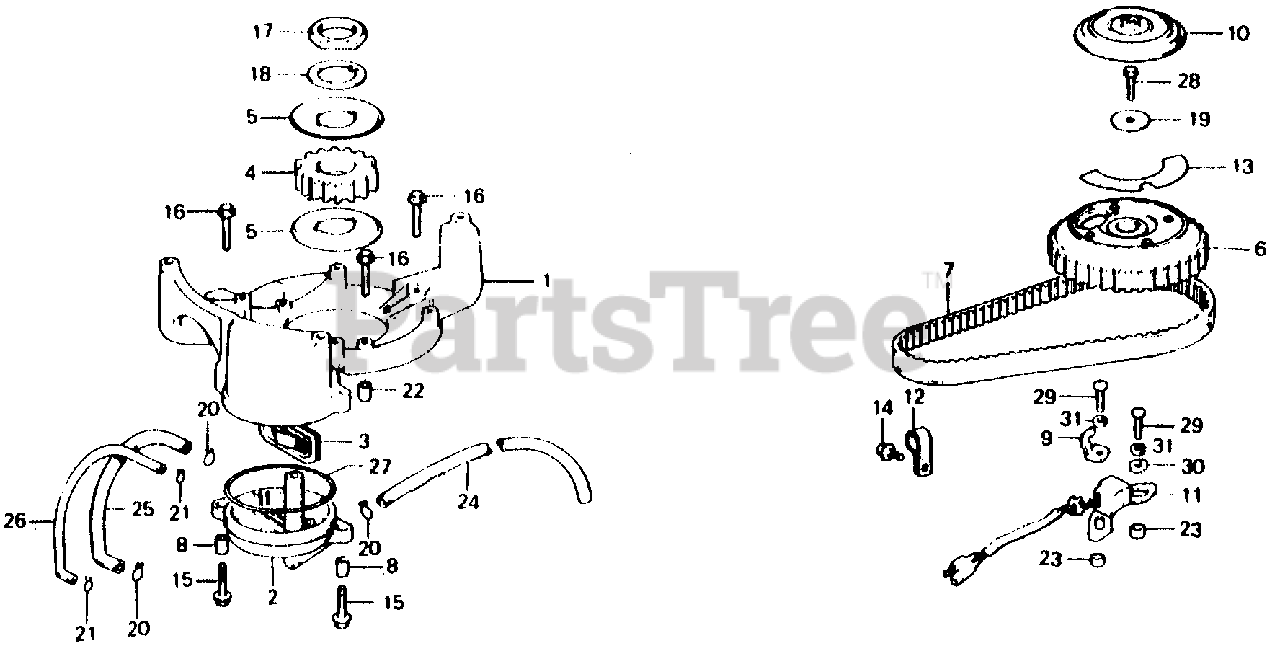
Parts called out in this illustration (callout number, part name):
1	CASE, STARTER *NH8* (DARK GRAY)
2	COVER, BREATHER
3	BODY, VALVE
4	PULLEY, TIMING
5	FLANGE, TIMING PULLEY
6	PULLEY, CAMSHAFT
7	BELT, TIMING
8	COLLAR A, DISTANCE
9	PLATE, WIRE CLAMP
10	COVER, POINT
11	COIL ASSY., PULSER (NOT AVAILABLE)
13	MARK, POINT
15	BOLT, FLANGE (6X22)
16	BOLT, FLANGE (6X28)
17	NUT, LOCK (24MM)
18	WASHER, LOCK (24MM)
19	WASHER, WHEEL (6MM)
20	CLIP, TUBE (B12)
21	CLIP B7, TUBE
22	PIN, DOWEL (8X10) (NOT AVAILABLE)
23	PIN, DOWEL (7X4.5)
24	TUBE B, BREATHER (NOT AVAILABLE)
25	TUBE C, BREATHER
26	TUBE, OIL RETURN
27	O-RING (62X2.5)
28	BOLT, HEX. (6X22)
29	SCREW, PAN (5X14)
30	WASHER, PLAIN (5MM)
31	WASHER, SPRING (5MM)
